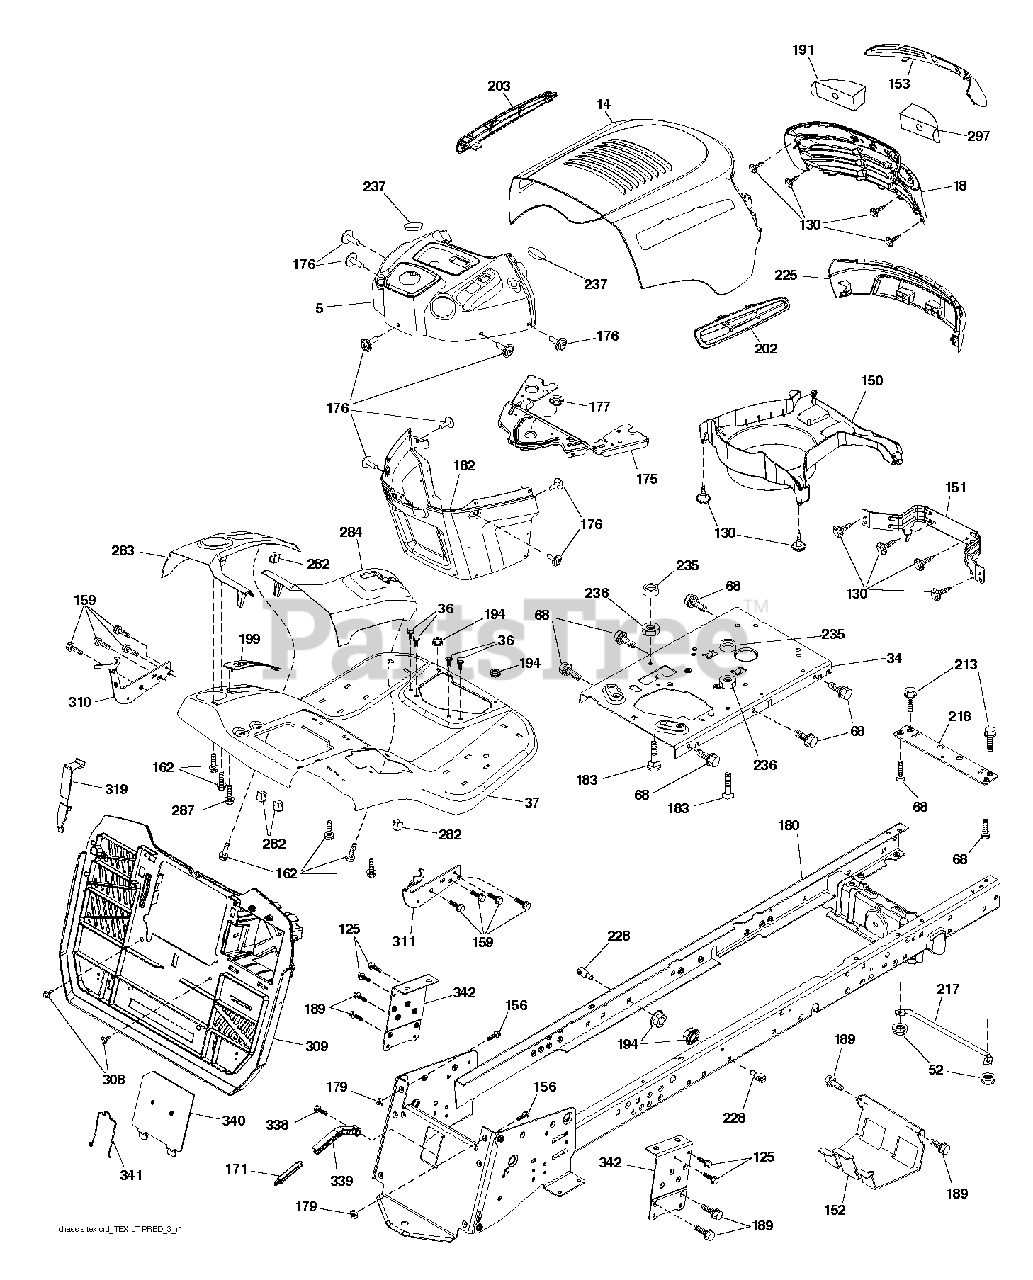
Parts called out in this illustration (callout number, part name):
34	PLATE.ENGINE.WELDED.CHASSIS
36	SCREW 5/16"
52	LOCKNUT
125	SCREW
130	SCREW.#10 X 0.750.BOS THREAD
151	BRACKET.PIVOT.ALPHA.LT
152	SHIELD BROWNING
156	BOLT
159	SCREW, 3/8-16X3/4
162	SCREW.HI-LO.CONSOLE
175	CROSSMEMBER
176	SCREW.#10-24X5/8.RN.QU
177	BUSHING STEERING
182	DASH.LWER.PREDATOR/HUSQ.LT
183	BOLT.5/16-18X1-1/4 FULL THD
189	SCREW
191	INSERT.REFLECT.PREDATOR.LT.RH
194	NUT LOCK HEX FLANGE 5/16-18
213	BOLT
217	ROD.PIVOT.HOOD
218	X-PIECE.HOOD.STOP.NON/
228	STUD.FASTNER.W/ANTI-ROTATE
235	SPACER FENDER
236	NUT.CENTERLOCK.5/16-
237	PLUG.MOUNT.CARGO.BLK
282	CLIP.RETAINER.CONSOLE.LT.HUSQ
297	REFLECTOR.INSERT.PRED.LH.LT
308	BOLT, 5/16-18 X 1 3/4
